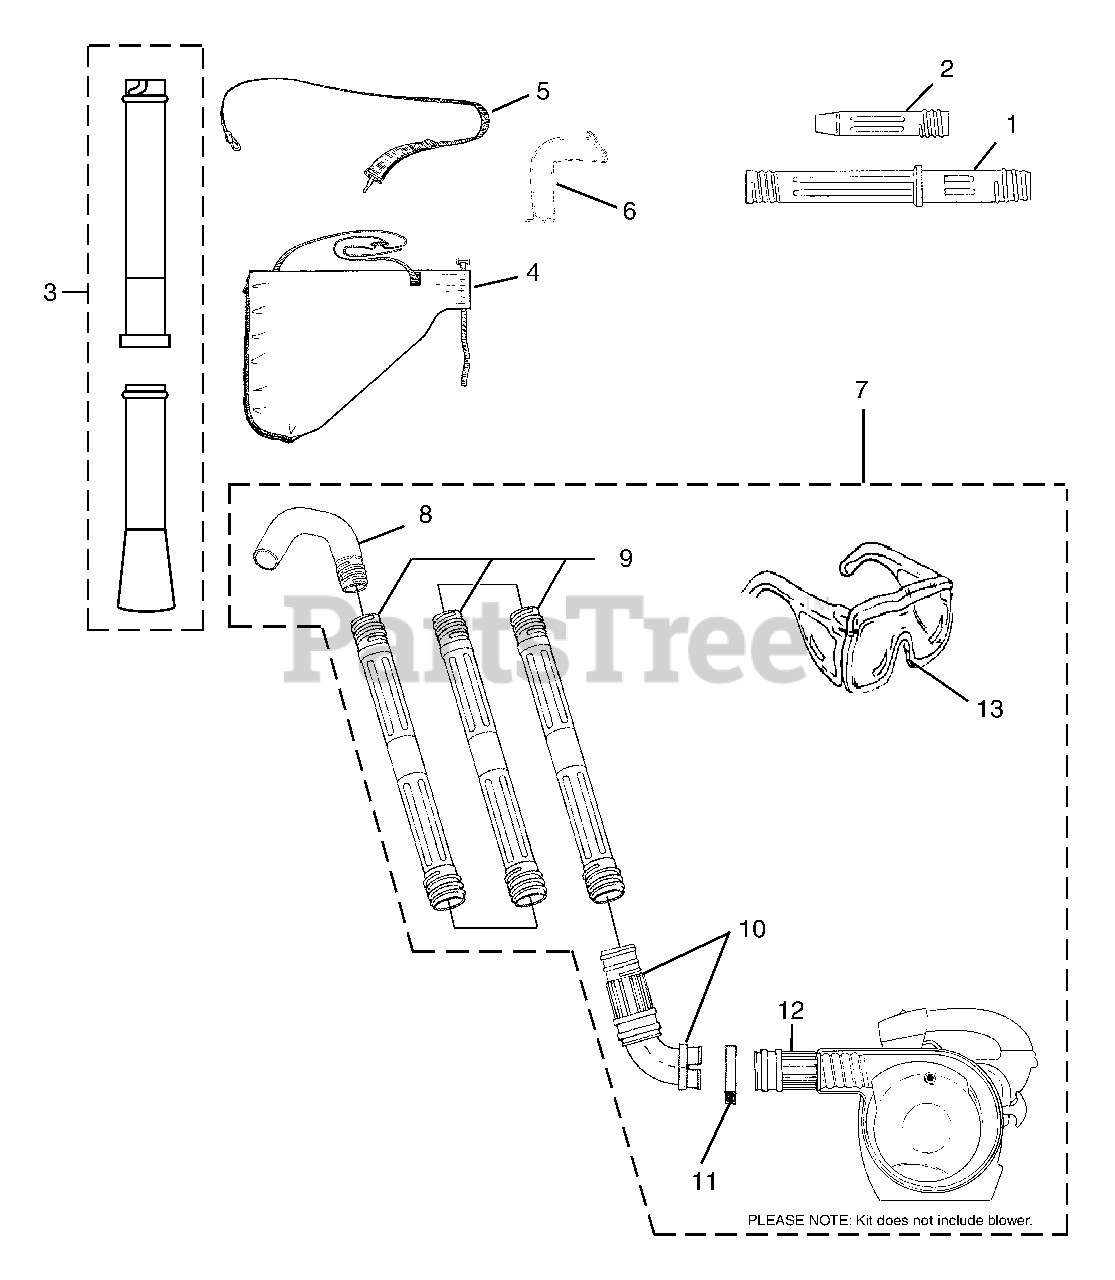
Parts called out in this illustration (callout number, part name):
1	Tube, Blower
2	Nozzle, Blower
3	Vac Tubes
5	Shoulder Strap
6	Air Deflector
7	Gutter Maintenance Kit
8	Full Elbow
9	Straight Tube
10	Upper Elbow & Swivel Adapter
11	Large Clamp
12	Adapter, Gutter
13	Safety Glasses - Clear
